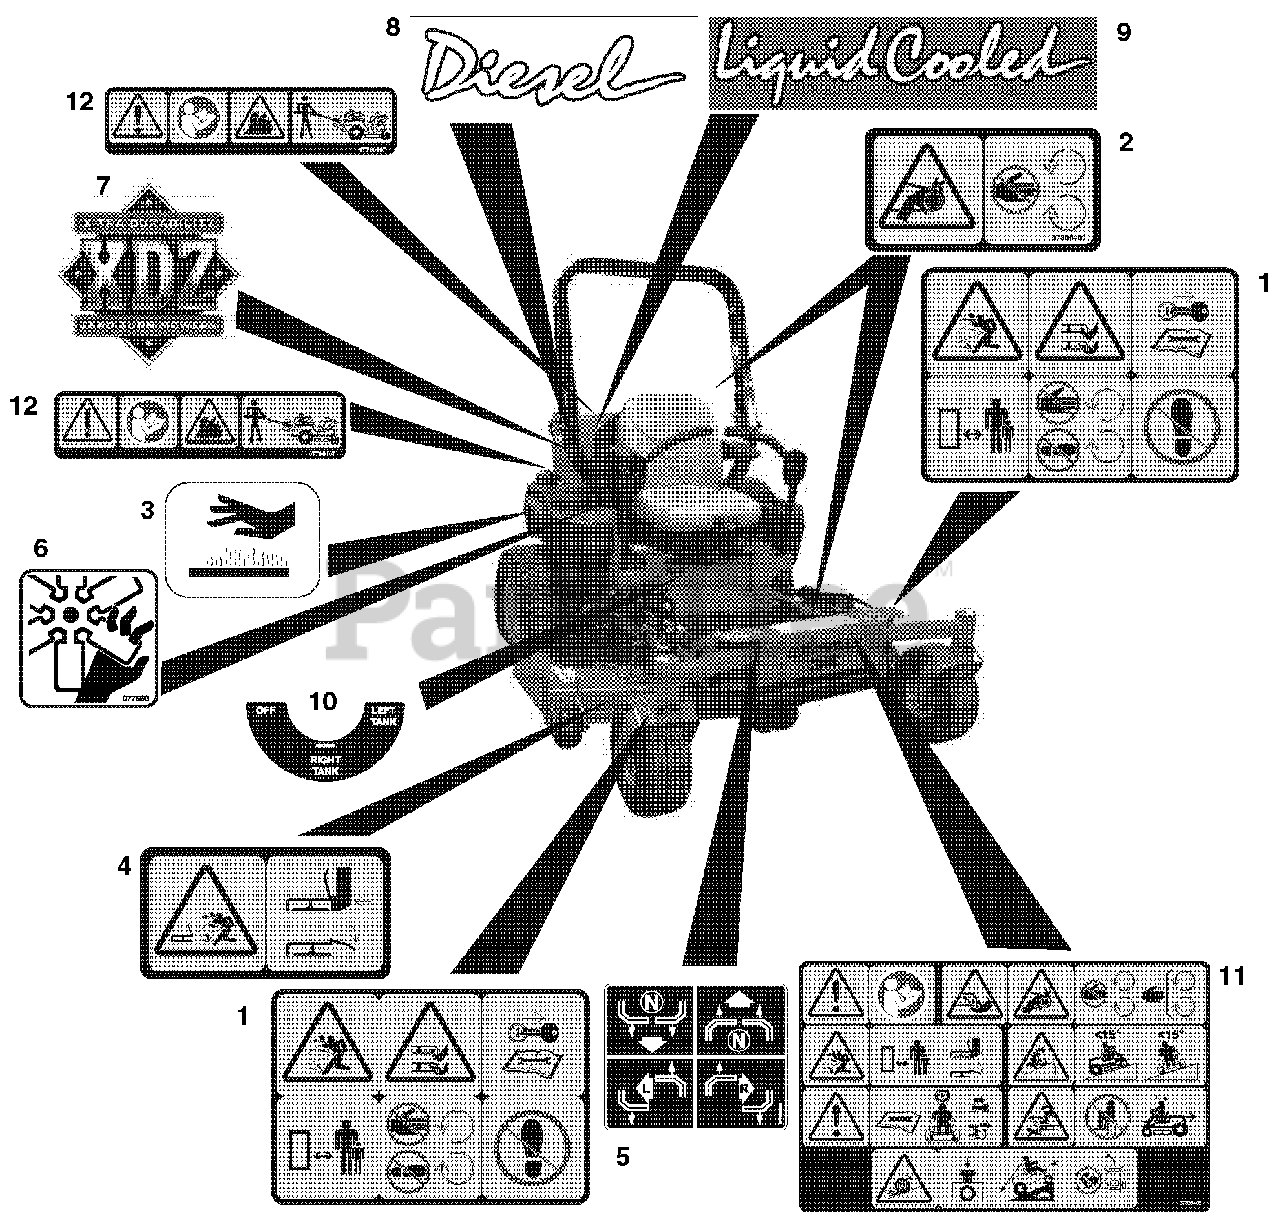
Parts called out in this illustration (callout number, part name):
1	Decal, Mower Deck
2	Decal, Safety Guarding
3	Decal, Hot Surface
4	Decal, Safety Deck Mounting
5	Decal, Instructional
6	Decal, Danger Fan
7	Decal, XDZ
8	Decal, Diesel
9	Decal, Liquid Cooled
10	Decal, Fuel Valve
11	Decal, Main Safety Commercial
12	Decal, Debris
